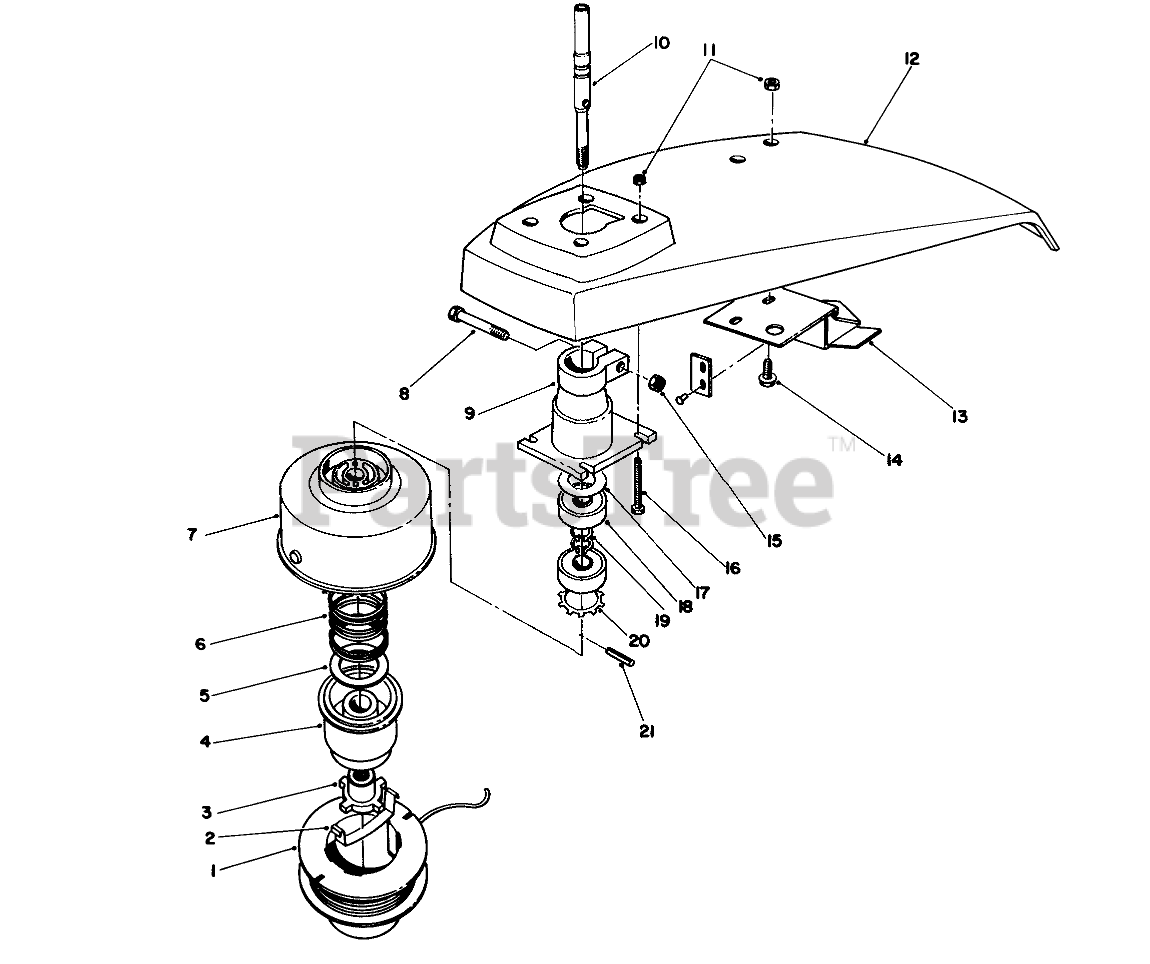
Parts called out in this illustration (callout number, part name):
1	Empty Spool
2	SADDLE-SPOOL CAP
3	DRIVER
4	SPOOL CORE
5	WASHER-FLAT
6	SPRING COMPRESSION
7	DRUM/EYELET
8	SCREW-HH
9	Housing-Bearing Assembly (Incl. Ref. #10, 17-21)
10	POWER SHAFT
11	NUT-LOCK, NI
12	GRASS SHIELD-PLASTIC
13	BRKT/KNIFE BLD ASM
14	SCREW-HWH
15	NUT-LOCK, NI
16	SCREW-HH
17	FLAT WASHER
18	BEARING-BALL
19	RING-SNAP
20	SPRING GRIP
21	COIL PIN
